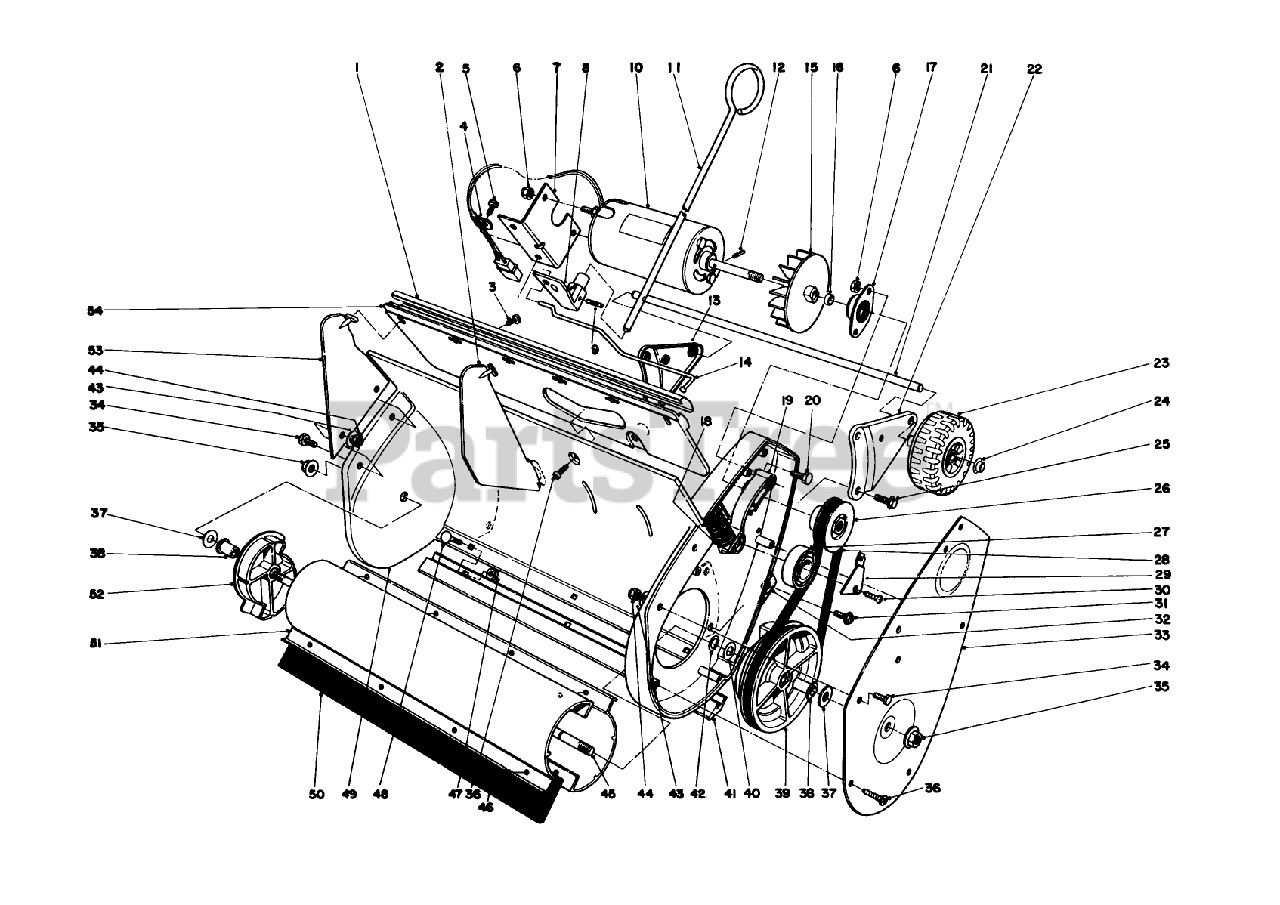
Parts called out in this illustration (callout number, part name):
3	10-16 X 3/8 THDG SCREW
4	CLIP-CLOSED, INSULATED
6	NUT-LOCK, NI
20	SCREW-HH
21	AXLE SHAFT
23	S-120 WHEEL
24	PUSHNUT-CAP, WASHER
27	BEARING-BALL
30	#8 X .625" PHILPS PAN H
31	SCREW-HWHTF
32	NUT-TYPE J
33	BELT CASE COVER
34	SCREW-HWH
35	NUT-HF
38	BUSHING ROTOR
40	WASHER-THRUST
42	RING-RETAINING
44	NUT-LOCK, NI
45	ROTOR SHAFT
46	TSCREW-HWH
47	NUT-KEPS
48	SCREW-CARR
49	HOUSING, S-120 HID
53	VANE OUTSIDE
